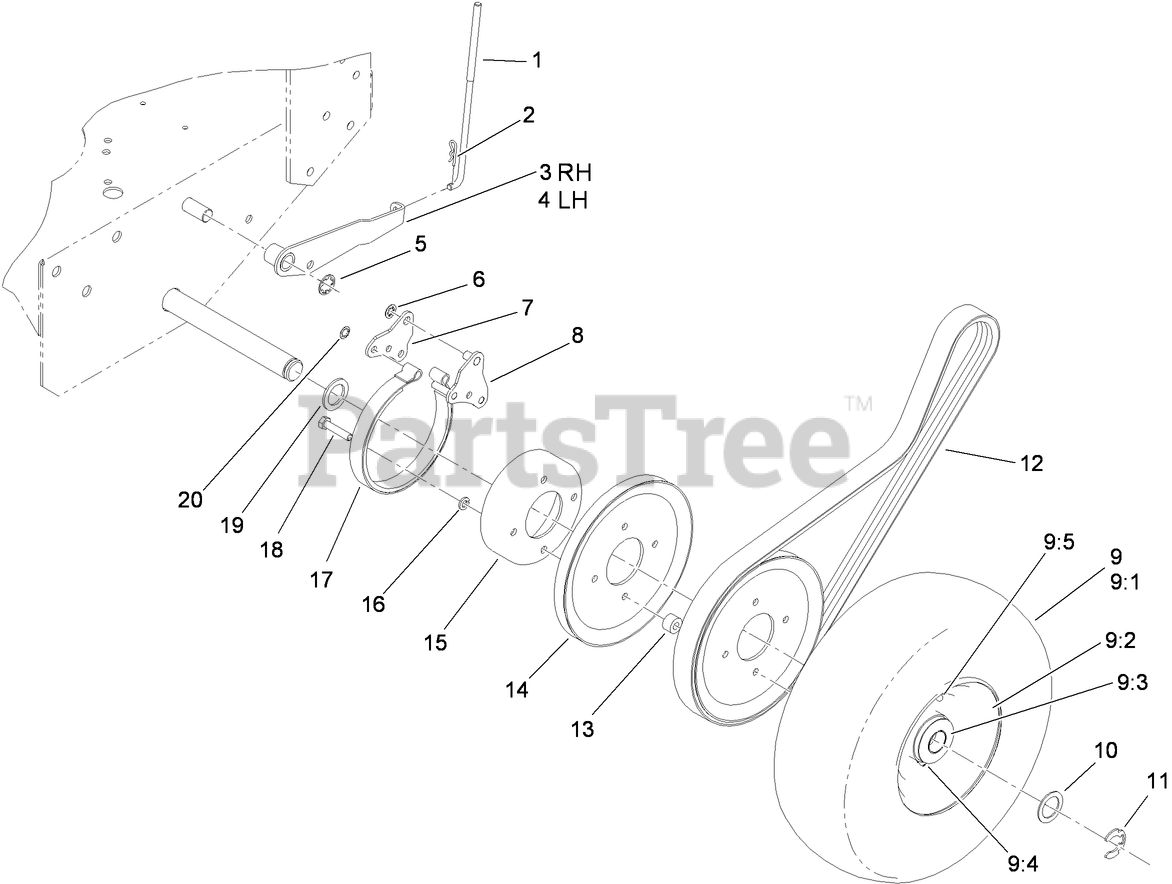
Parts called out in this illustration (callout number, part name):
1	ROD-BRAKE
2	PIN-COTTER
3	ARM-BRAKE, RH
4	ARM-BRAKE, LH
5	RING-RETAINING
6	RING-RETAINING, EXTERNAL
7	PLATE-LINK, BRAKE
8	LINK-BRAKE
9	WHEEL AND TIRE ASM
9:1	TIRE-FRONT
9:2	WHEEL ASM
9:3	BEARING-BALL
9:4	FITTING-GREASE
9:5	STEM-VALVE
10	WASHER-THRUST
11	RING-RETAINING
12	V-BELT
13	SPACER-PULLEY
14	PULLEY-WHEEL
15	DRUM-BRAKE
16	WASHER-LOCK
17	BAND-BRAKE
18	SCREW-HH
19	WASHER-WHEEL
20	RING-RETAINING
